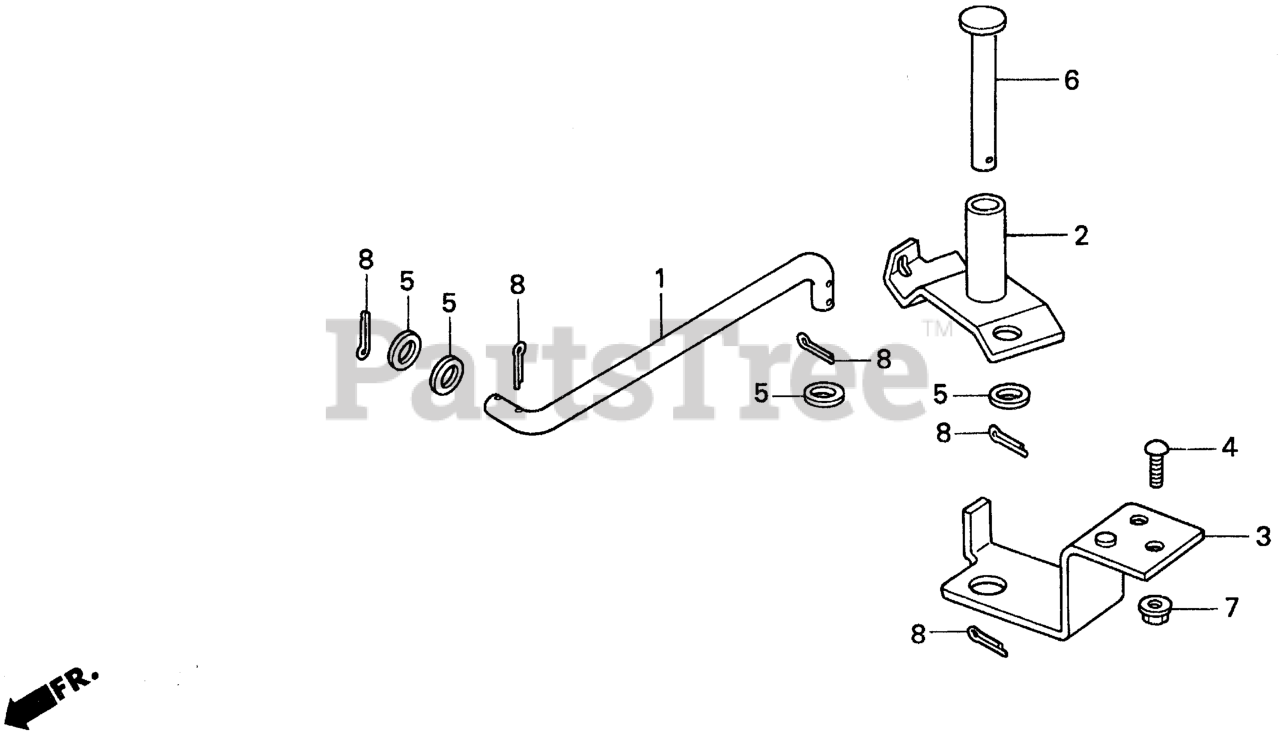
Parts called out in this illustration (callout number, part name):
1	ROD, P.T.O. CLUTCH
2	ARM, P.T.O.
3	BASE, PLATE P.T.O. ARM
4	BOLT, SPECIAL (8X20)
5	WASHER (13X20)
6	PIN, P.T.O. ARM
7	NUT, FLANGE (8MM)
8	PIN, COTTER (2.5MM)
